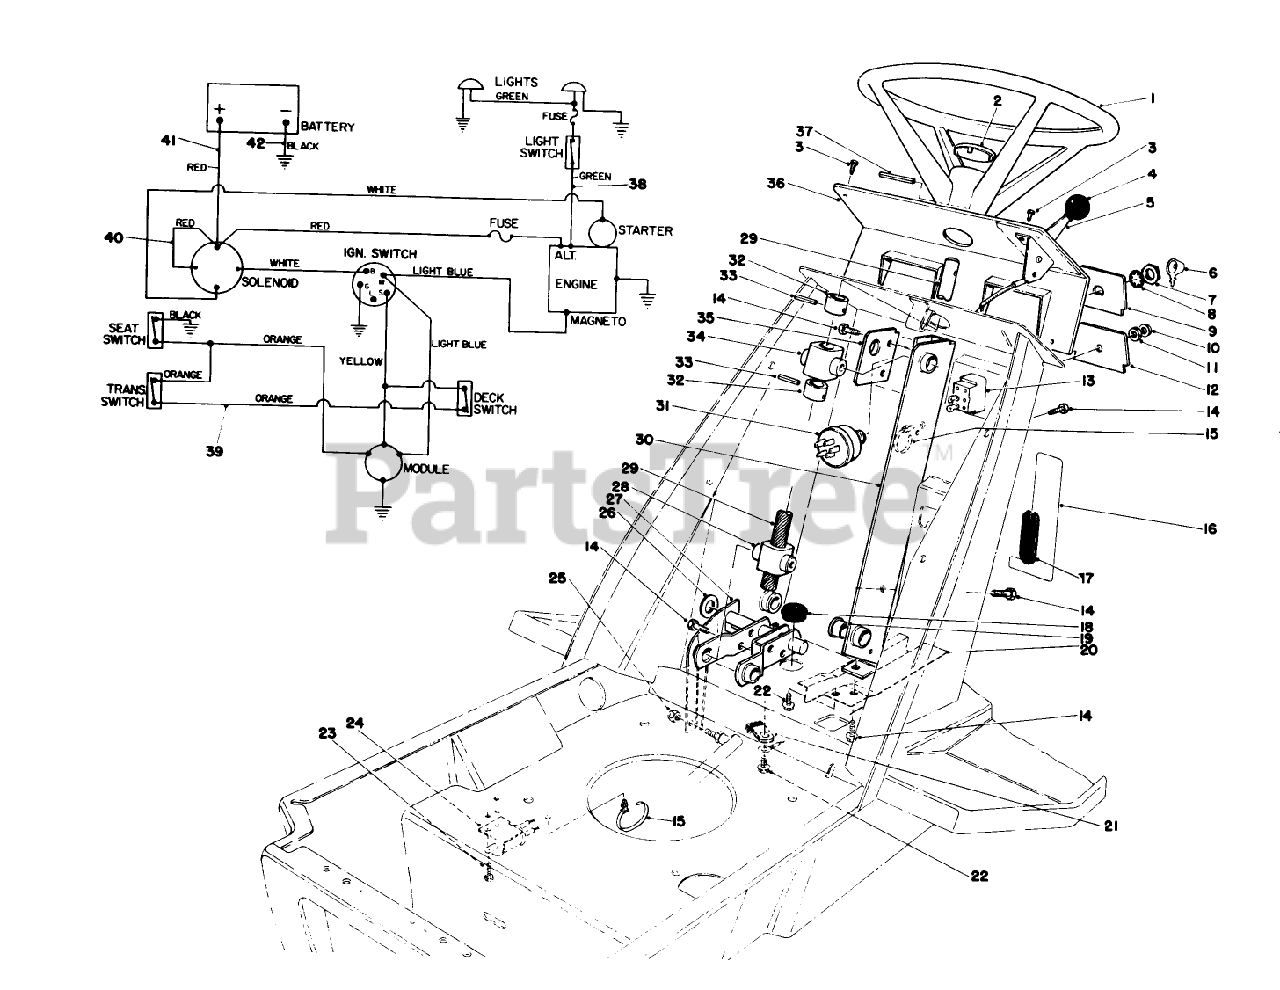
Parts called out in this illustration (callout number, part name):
3	SCREW-HWHTF
4	KNOB-CONTROL
5	THROTTLE CONTROL
7	NUT-HH
8	WASHER-LOCK
11	NUT-LOCK
13	SWITCH-LIGHT
14	SCREW-THD ROLL, HWH
15	TIE-MOUNT, PUSH
18	GROMMET
19	BEARING-FLANGE
21	CLIP-FUEL LINE
22	SCREW-HWH
23	SCREW-TAPTITE
24	Switch-Interlock
29	STEERING SHAFT
31	SWITCH-STARTER
32	STRG SHAFT COLLAR
33	PIN-SPRING
37	PIN-ROLL
41	WIRE ASM
42	WIRE ASM
